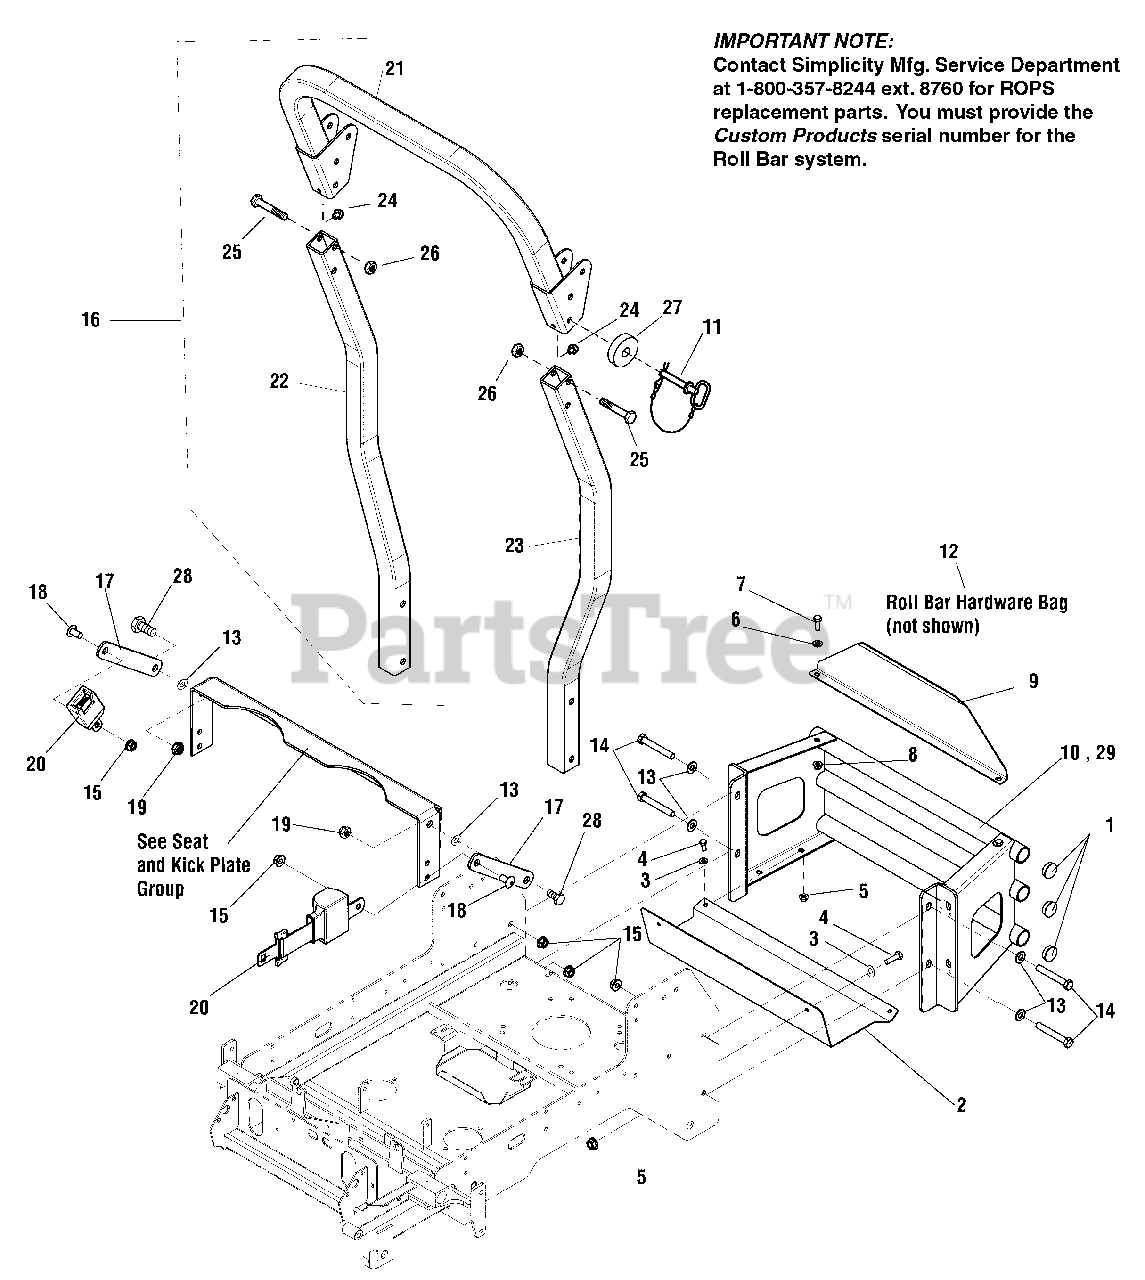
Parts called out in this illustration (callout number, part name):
1	PLUG, PANEL, 1.25 - BLACK
2	PLATE, HEAT SHIELD - BLK
3	WASHER, 5/16" SAE
4	BOLT, 5/16-18 X 3/4 GD5
5	NUT, 5/16-18 HEX NYLOCK FLANGE
6	WASHER, 3/8 SAE
7	BOLT, 3/8-16 X 1 GD5 YZ
8	NUT, 3/8-16 HEX NYLOCK FLANGE
9	PLATE, CARB PROTECTOR - ORG
10	WELD, BUMPER - ORG
11	PIN, HITCH, BLACK W/ PLASTIC LANYARD
12	ROLL BAR HARDWARE BAG
13	WASHER, 1/2 SAE
14	BOLT, 1/2-13 X 3-1/4, HEX HD, GD5, YZ
15	NUT, 1/2-13 HEX NYLOCK FLANGE
16	ROPS (Call 1-800-933-6175 x708 if replacing a ROPS)
17	PLATE, SEAT BELT ANCHOR - BLK
18	SCREW, 1/2-13 X 1.00, SHCS
19	NUT, 1/2-13 HEX NYLON LOCK
20	SEAT BELT, RETRACTING - ASSM
21	ROLL BAR TOP LOOP
22	ROLL BAR POST, RH
23	ROLL BAR POST, LH
24	RUBBER BUMPER
25	*BOLT
26	*NUT
27	RUBBER WASHER
28	BOLT, 1/2-13 X 1-1/4 GD5 YZ
29	WELD, BUMPER - ORG
